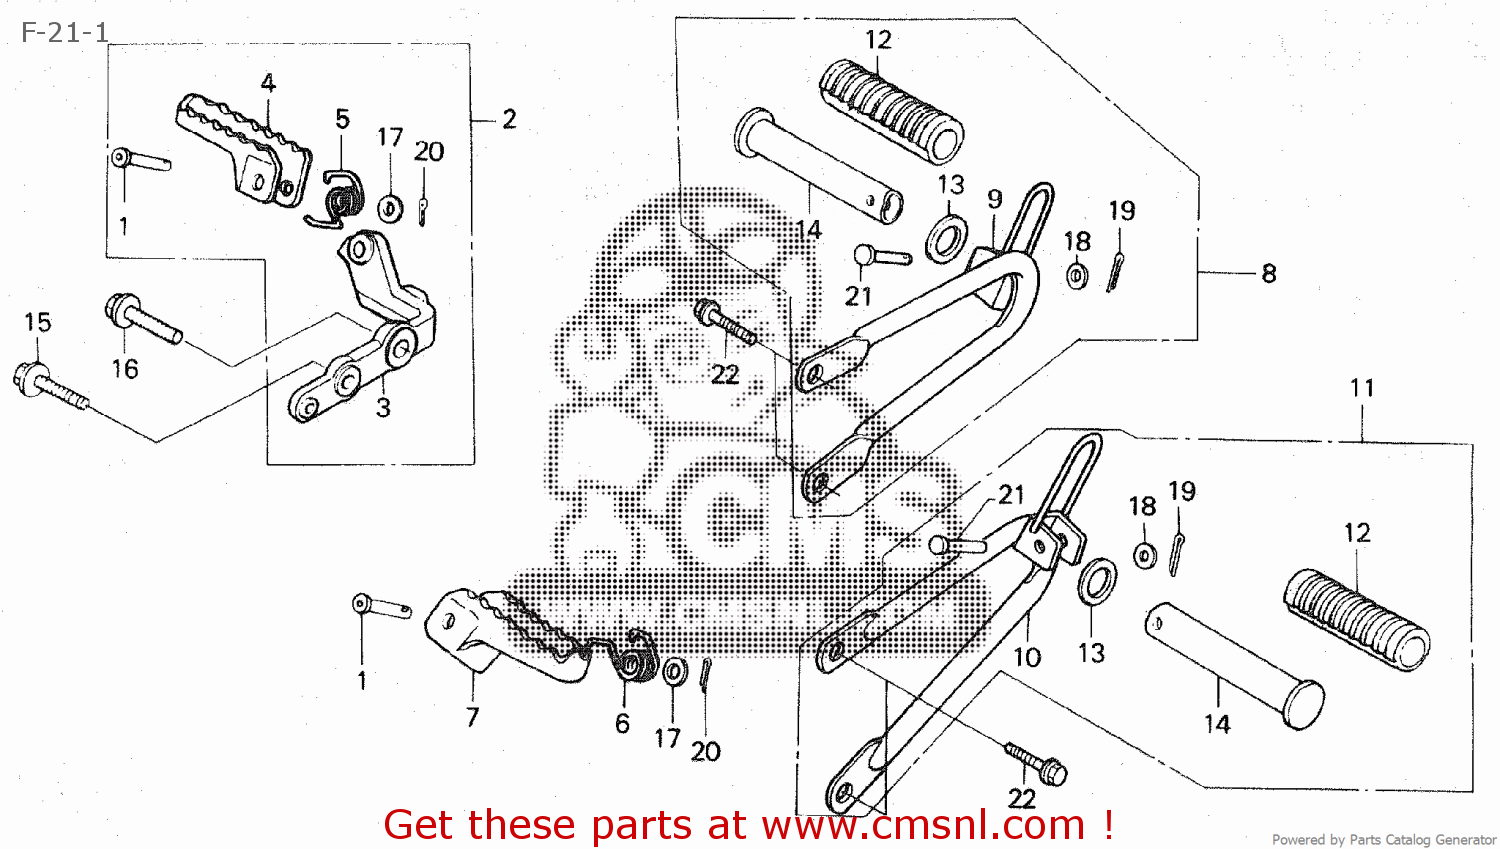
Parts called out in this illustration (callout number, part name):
1	PIN,STEP BAR JOIN
2	ARM ASSY.,R.STEP
3	ARM,R.STEP
4	STEP COMP.,R.
5	SPRING,R.STEP RET
6	SPRING,L.STEP RET
7	STEP COMP.,L.
8	STEP ASSY.,R.PILL
9	BRACKET, R.
10	BRACKET, L.
11	STEP, L. PILLION
12	RUB,PILLION STEP
13	PLATE,PILLION STE
14	BAR,PILLION STEP
15	BOLT,FLANGE 10X40
16	BOLT,FLANGE 12X40
17	WASHER,10.2MM
18	WASHER,PLAIN, 6MM
19	PIN,COTTER 1.6X15
20	PIN,COTTER 2.0X15
21	PIN,PILLION STEP
22	BOLT,FLANGE DR 8X
